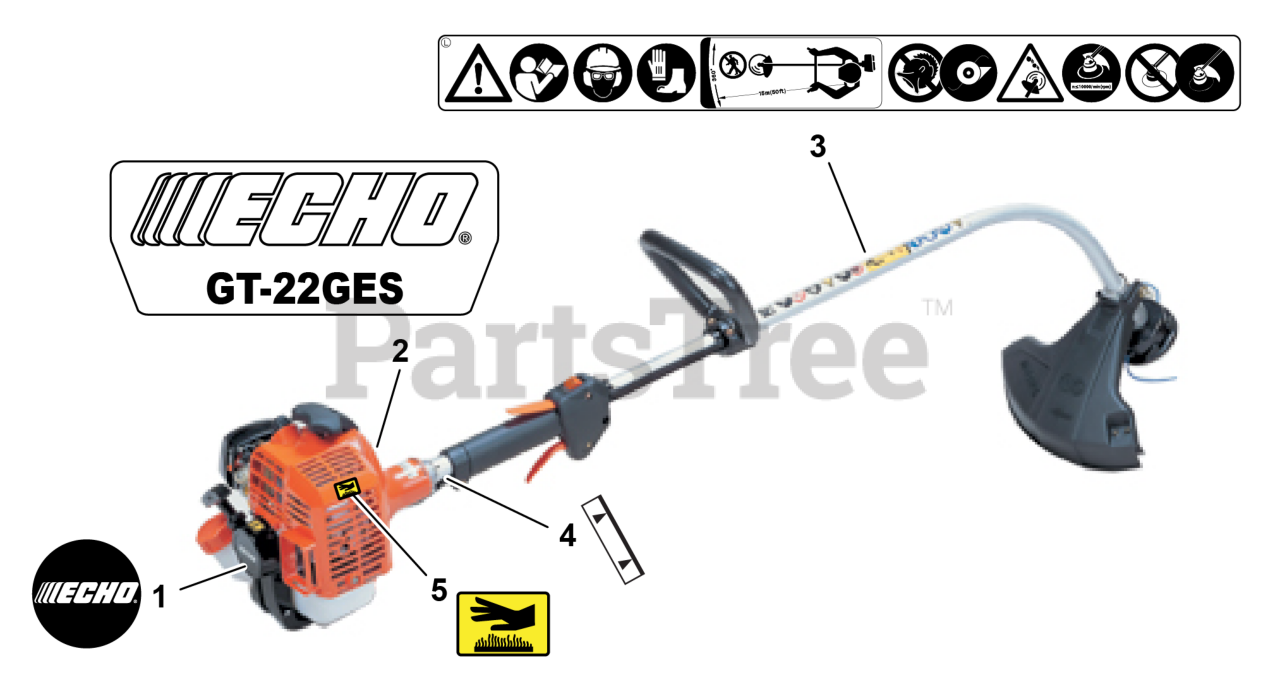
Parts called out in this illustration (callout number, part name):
1	LABEL - RECOIL STARTER
2	LABEL - GT-22GES
3	LABEL - ISO CAUTION
4	LABEL - ALIGNMENT
5	LABEL - CAUTION - HOT
